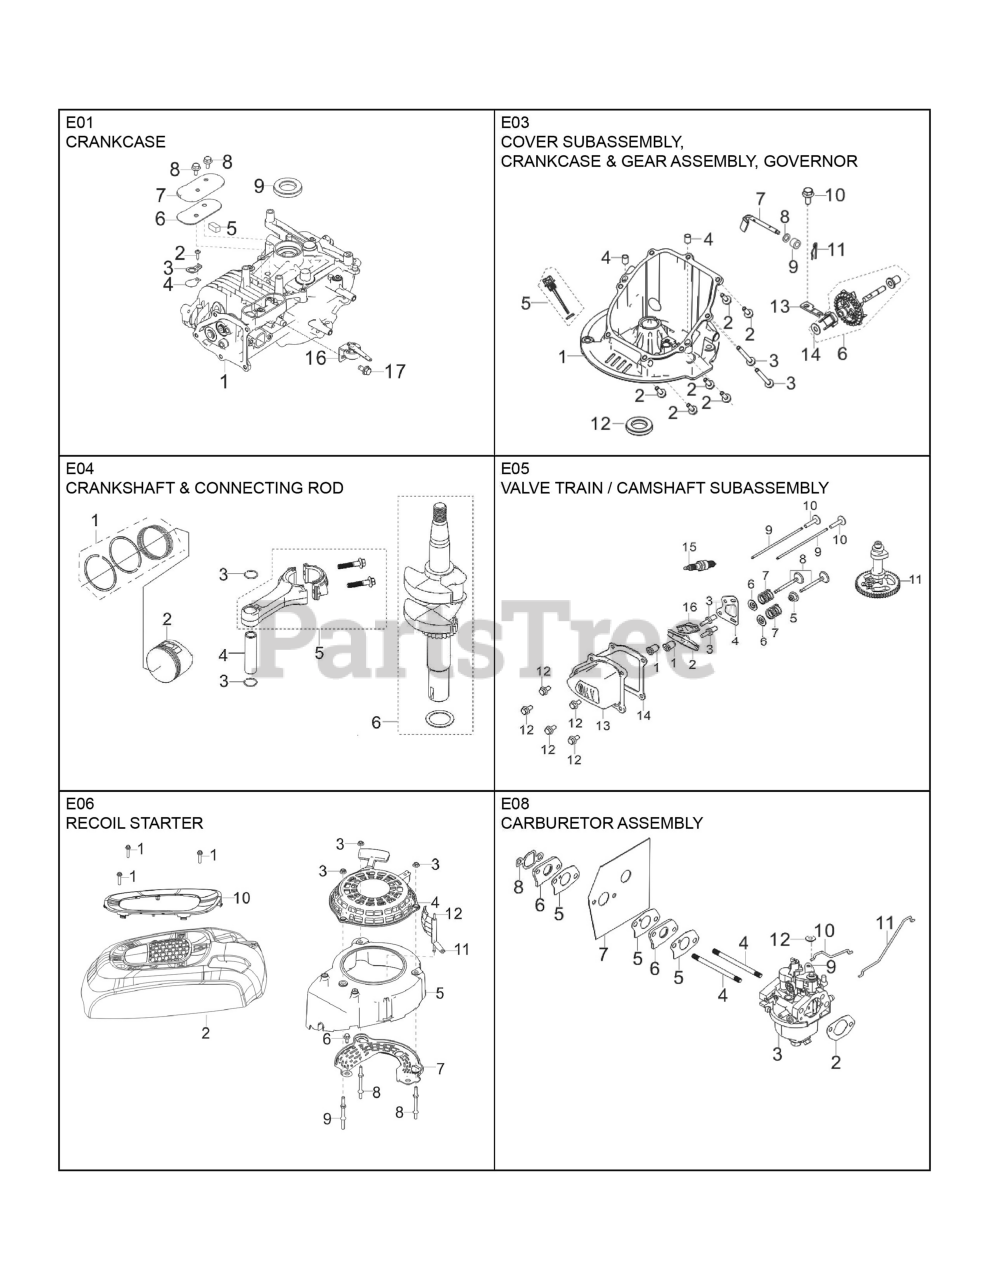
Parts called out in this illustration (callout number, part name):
E08	CARBURETTOR KIT RV175 CARBURET
E01	CRANKCASE RV175 CRANKCASE
E05	CAMSHAFT RV175 CAMSHAFT AND VA
E04	PISTON ASSY RV175 PISTON AND R
E03	CRANKSHAFT SYSTEM RV175 CRANKC
